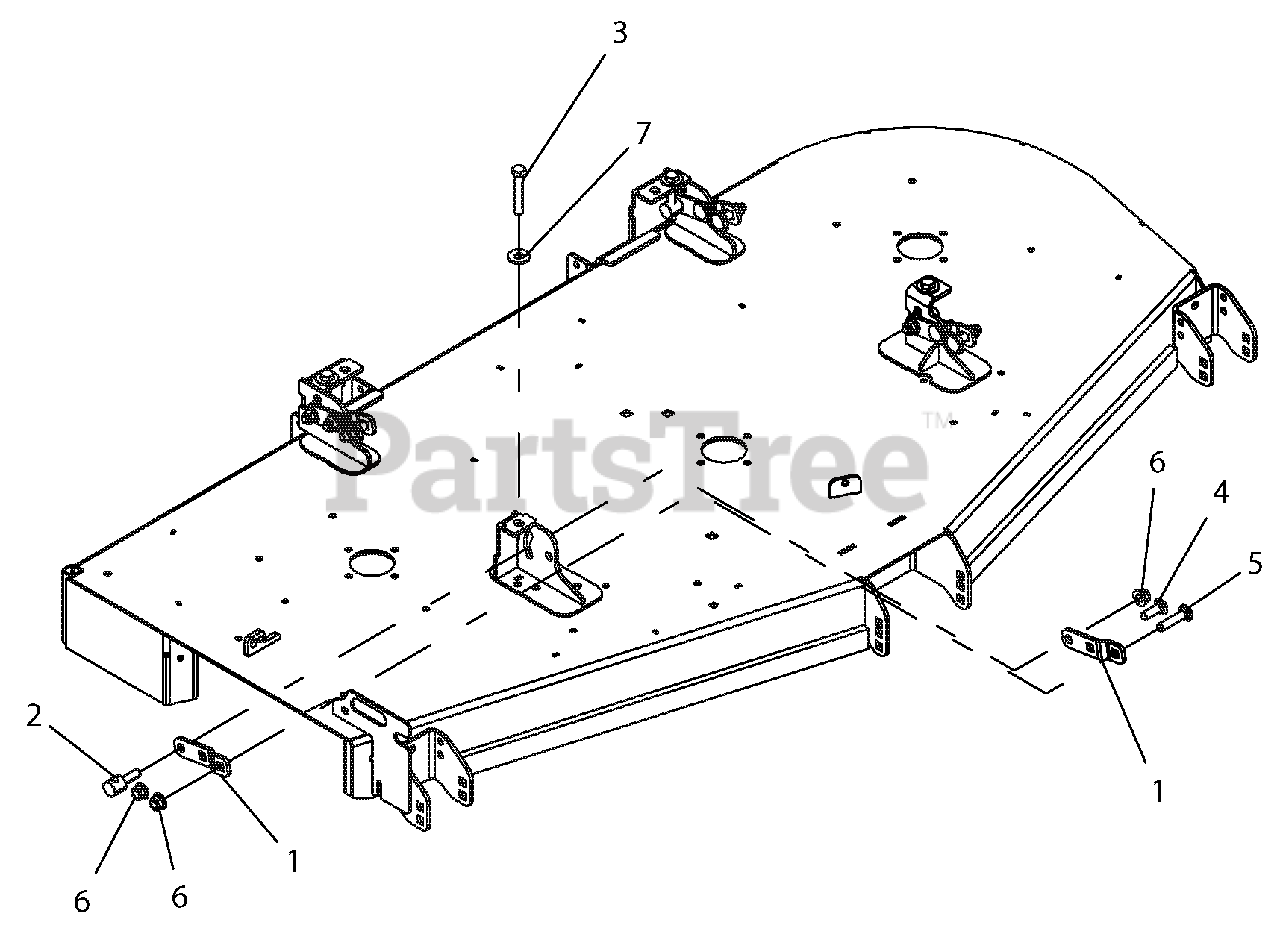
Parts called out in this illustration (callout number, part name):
1	BRKT, DECK LEVELING-BLACK
2	TRUNNION, .50-13
3	BLT, HEX .500-13 X 3.000 GR5 FTH YZ W/NYLON PATCH
4	BLT-RDHDSQNK .50-13X1.50 G5 YWZC
5	BLT-RDHDSQNK .50-13X2.25 G5 Y
6	NUT-LK-NYL-FLG .50-13 YWZC
7	WSHR-FL-STL.563X1.38X.109YWZC
